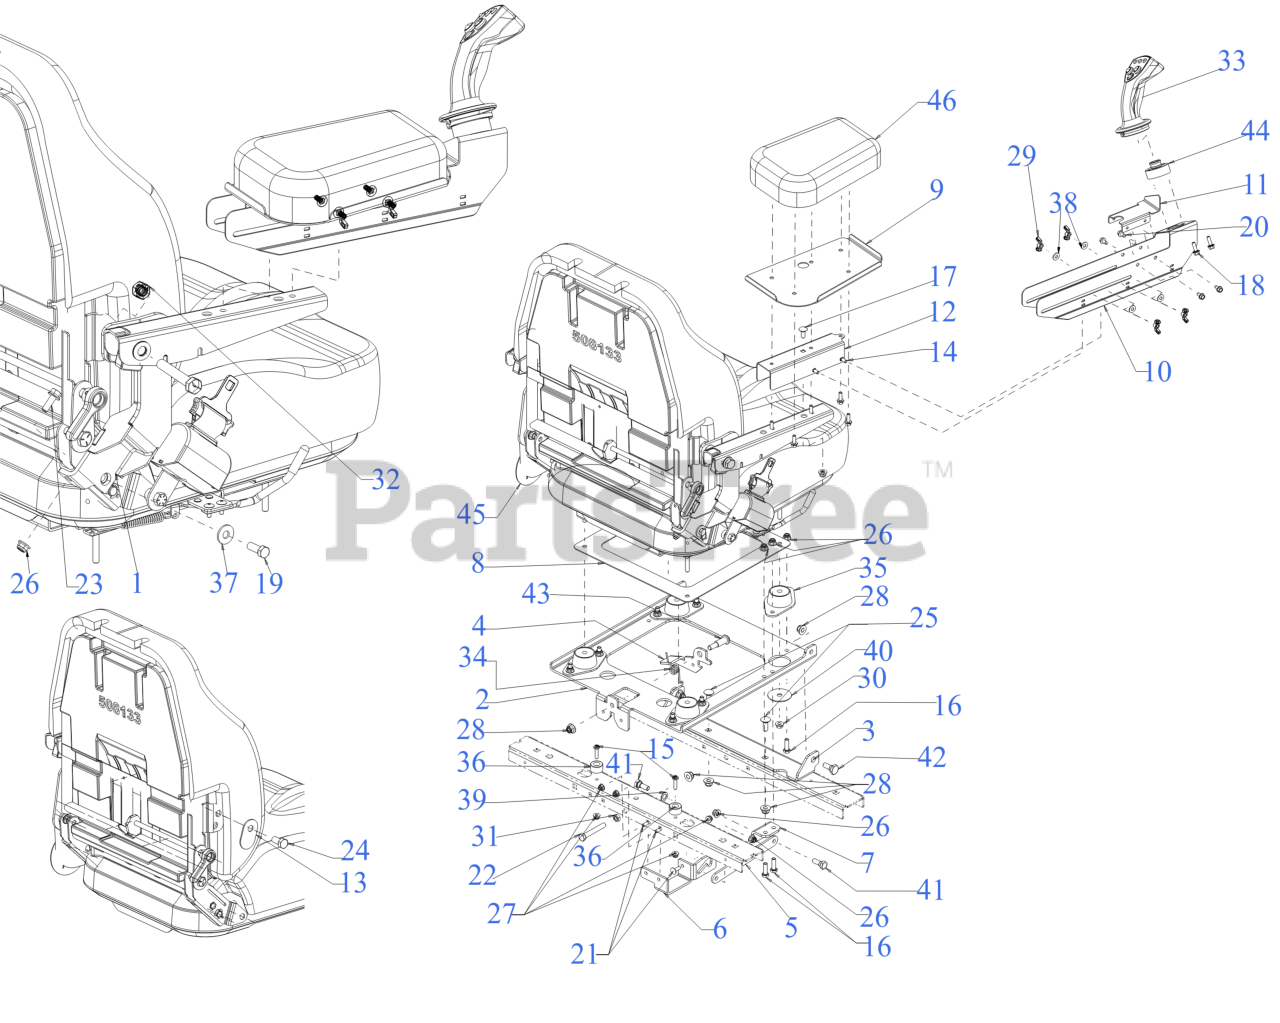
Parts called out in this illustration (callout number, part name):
1	ARMREST MOUNT (RH)
2	SEAT MOUNTING BRACKET
4	SEAT LATCH LEVER
5	SEAT LOCKOUT BRACKET
6	SEAT LOCKOUT MOUNT
9	PAD MOUNT PLATE
10	ARMREST BRACKET (RH)
11	JOYSTICK COVER BRACKET
12	ARMREST BRACKET
13	ARMREST COVER PLATE
14	CARRIAGE BOLT 1/4-20 x .62
15	MACHINE SCREW 1/4-20:1
16	SCREW 5/16-18 x 1.0 GR5
17	CARRIAGE BOLT 5/16-18 x .75
18	SCREW 1/4-20 x .75 GR5
19	SCREW 3/8-16 x 1 GR5
20	SCREW 1/4-20 X.500
21	SCREW 1/4-20 x .75 GR5
22	HEX SCREW-3/8-16X2.5 GR5
23	SCREW 5/16-18 x .875 GR5 HXFLG HD
24	SCREW 1/2-13 x 1.0 GR5
25	CARRIAGE BOLT 3/8-16 x 1.00 GR5
26	FLANGE LOCK NUT 5/16-18
27	FLANGE LOCK NUT
29	WING NUT 1/4-20
30	HEX FLANGE NUT
31	HEX JAM NUT 3/8-16 GR5
32	HEX NUT CTR LK 1/2-13
34	TORSION SPRING
35	SEAT MOUNT
37	WASHER .406X1.0X.095
38	FLAT WASHER .271:.630:.065
39	FLAT WASHER .469X.750X.054
40	HUB CAP WASHER .406 x 1.92 x .060
41	SHOULDER SCREW .437
42	SHOULDER SCREW
43	SHOULDER SCREW .50X.925
44	JOYSTICK MOUNT
45	SEAT (ELEC LUMBAR)
46	ARMREST PAD
